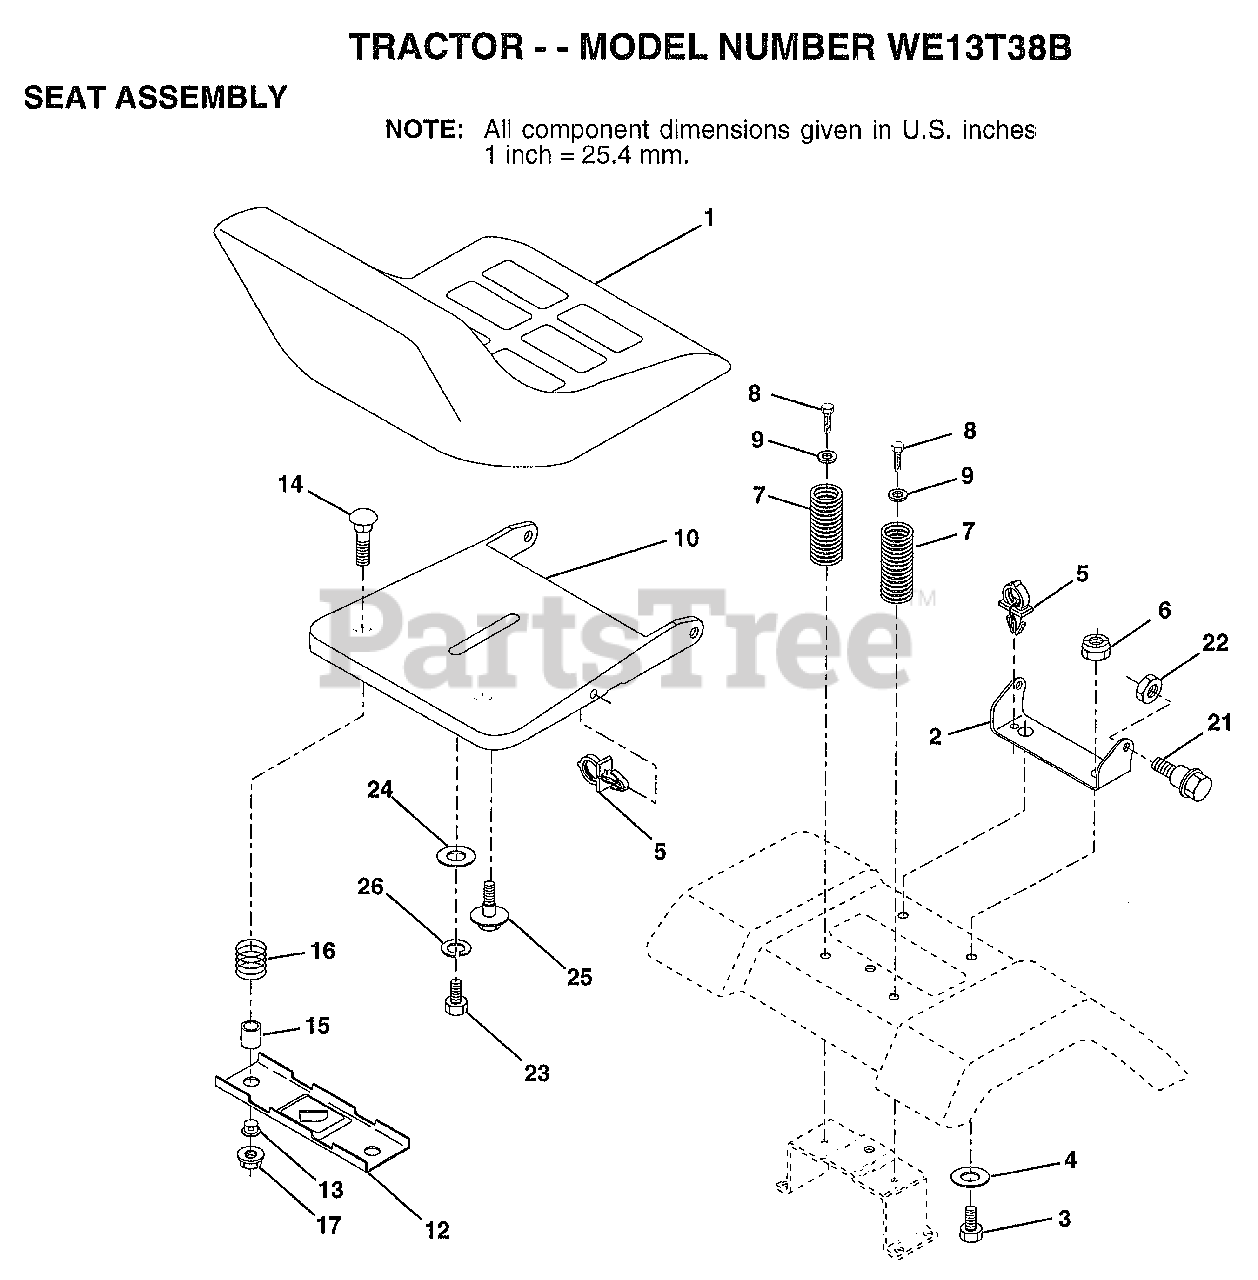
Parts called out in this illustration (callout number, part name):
2	BRACKET PVT SEAT
3	BOLT
4	WASHER PM
5	CLIP.PUSH-IN.HING
6	NUT
7	SPRING COMPRESSIO
8	SCREW GTV
9	WASHER
10	PAN-SEAT
12	BRKT SWITCH
13	BUSHING
14	BOLT-RD HD SQ NK
15	SPLIT SPACER
16	SPRING
21	"BOLT,SHOULDER"
22	NUT
23	BOLT
24	WASHER
25	"BOLT,SHOULDER"
26	LOCKWASHER
